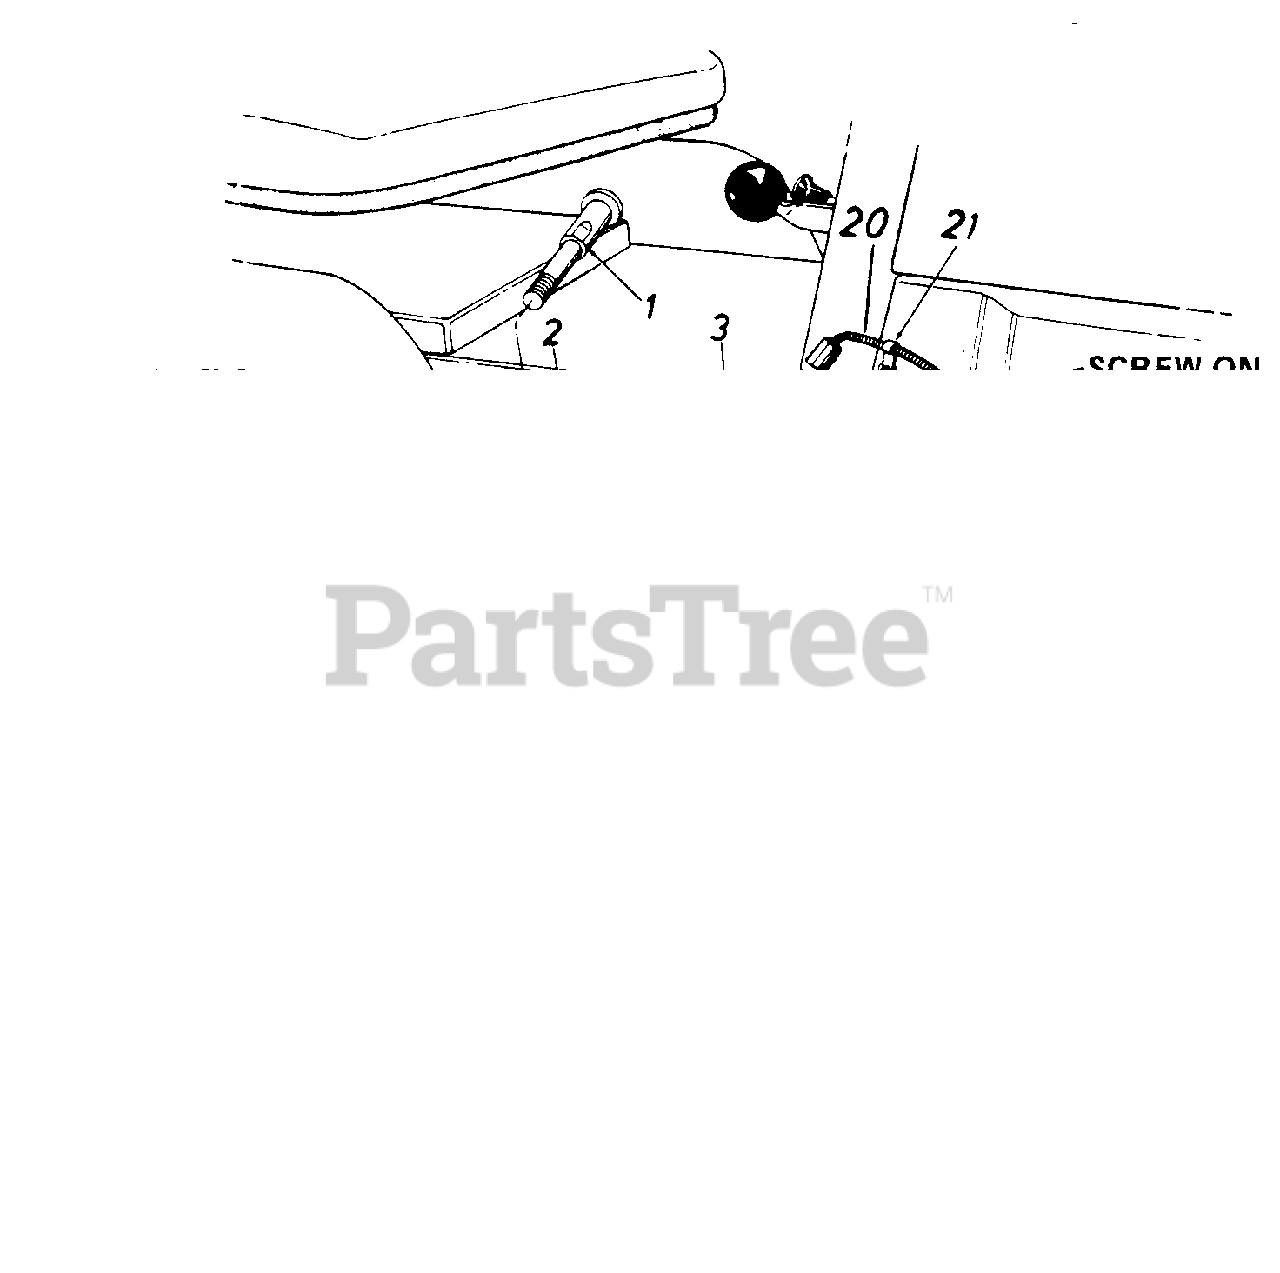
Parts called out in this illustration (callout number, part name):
1	Pivot Pin
2	Shld. Bolt .626 Dia. x .96"
5	Hex Nut 1/4-28 Thd.
6	L-Wash. 1/4" I.D.
7	Hex Bolt 1/4-28 x .75" Lg. (Grade 5)
8	Cotter Pin
9	Indicator & Mtg. Pin
10	Electric Actuator
12	Hex Jam Nut 1/2-13 Thd.
13	Lift Shaft Drive
16	HexBolt 5/16-24x 1.0" Lg. (Grade 5)
17	Fl-Wash. .53" I.D. x.93" O.C
18	L-Wash. 1/2" I.D.
20	Plastic Tubing-7"
21	Clamp
